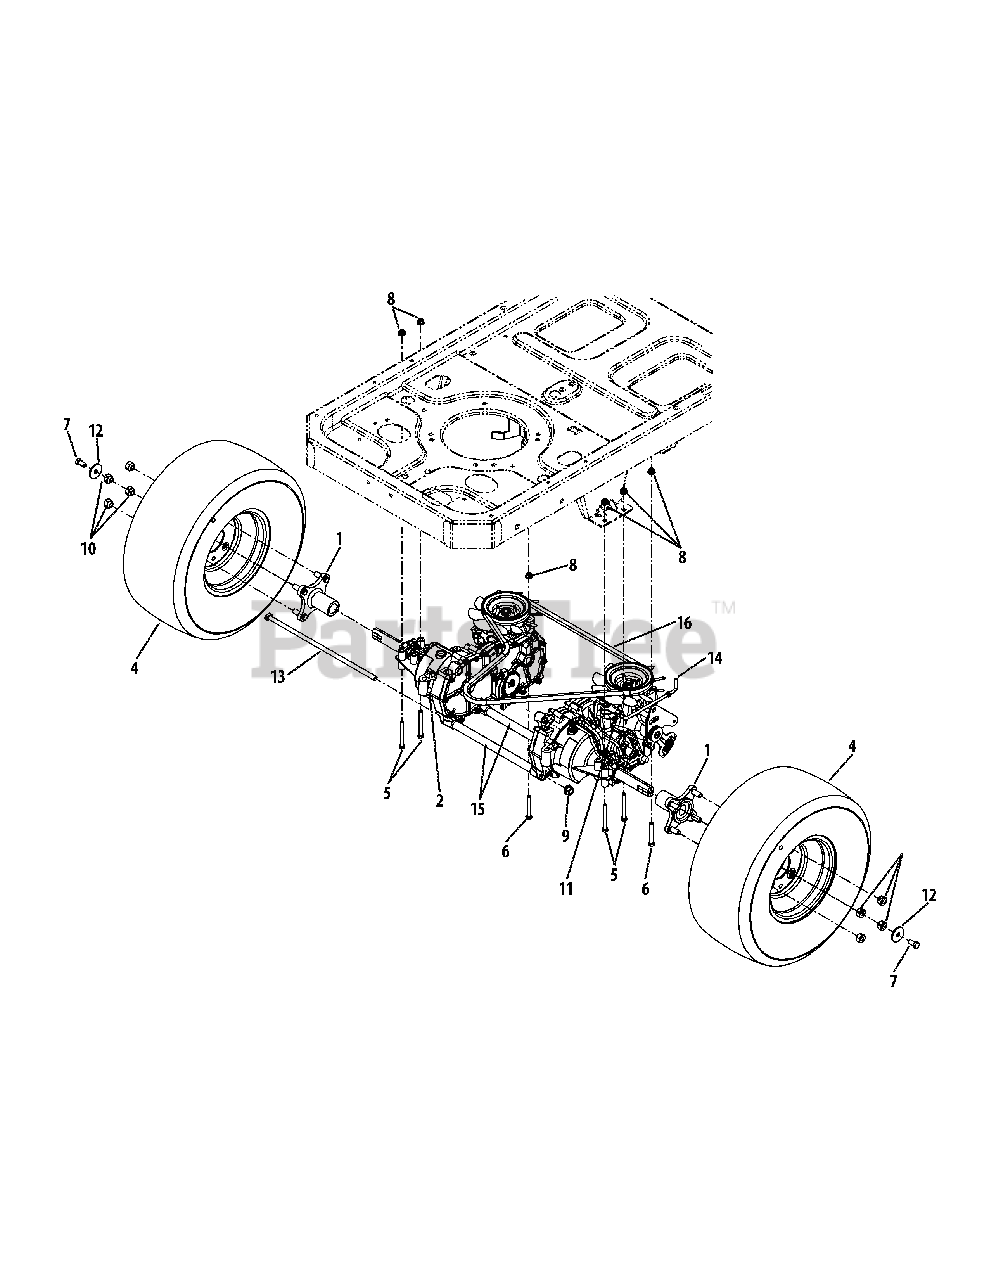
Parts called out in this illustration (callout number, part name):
1	Hub, Wheel Double D Long 3"
1	Hub, Wheel Double D Short 2.5"
2	Transmission Assembly (LH) Double D axle
2	Transmission Assembly (RH) Double D axle
4	Wheel Assembly, 18 x 8.5 x 8 (42" deck)
4	Wheel Assembly, 18 x 9.5 x 8 (50" deck)
5	Hex Cap Screw, 5/16-18 x 2.75
6	Hex Cap Screw, 5/16-18 x 2.25
7	Hex Cap Screw Lock, 3/8-16 x .75
8	Hx Flnge Insert Lck Nut, 5/16-18
9	Hex Flange Lock Nut, 7/16-20
10	Lug Nut, 7/16-14
11	Cotter Pin, 3/32 x .75
12	Flat Washer, .39 x 1.5 .134
13	Rod, .405 x 14.0
15	Tube, .45 x .69 x 10.2
16	Type A Sec V-Belt x 57.7
